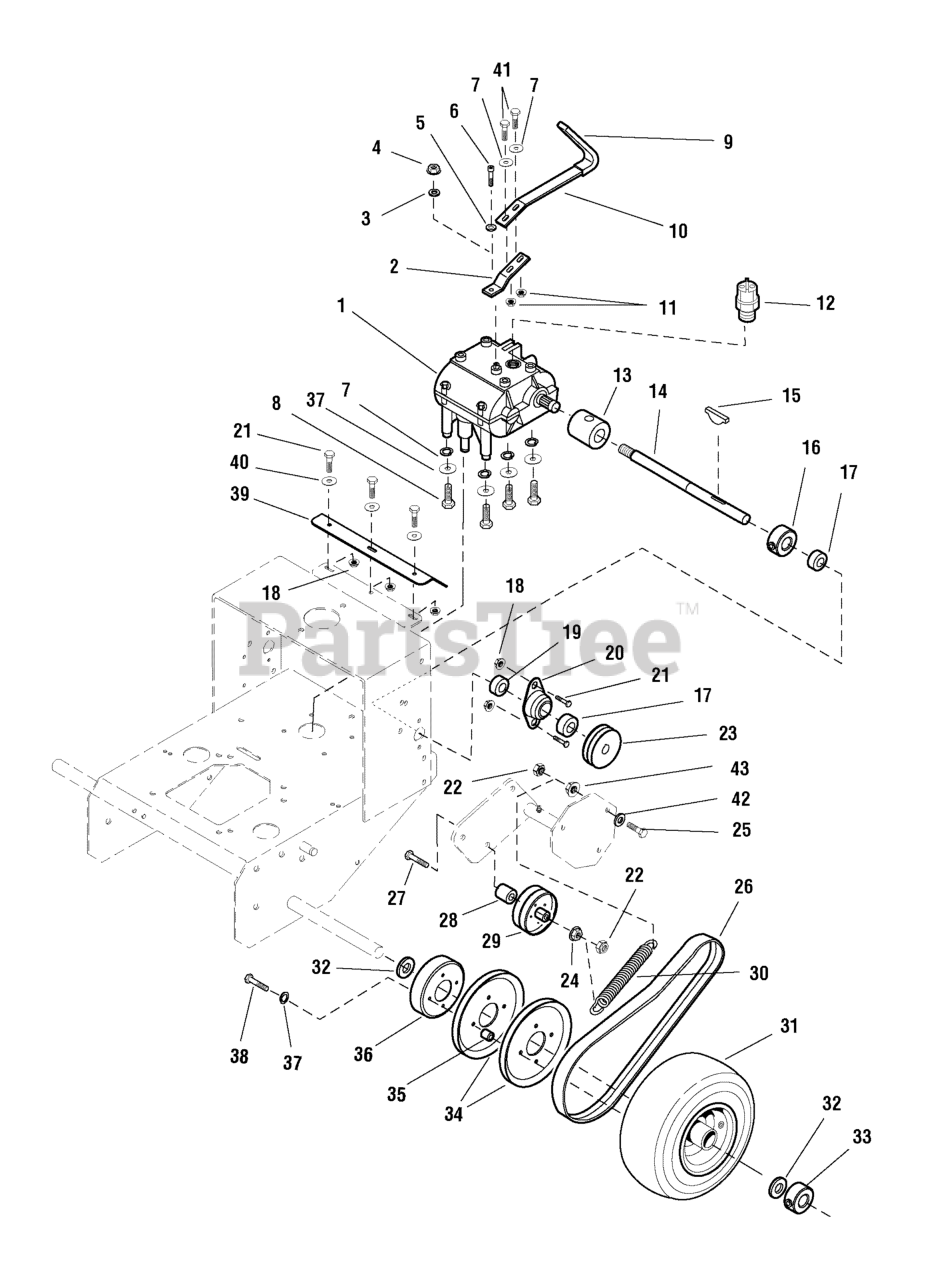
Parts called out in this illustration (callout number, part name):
1A	5 SPEED GEARBOX
1B	5 SPEED GEARBOX
2A	LEVER, Gear Selector
2B	LEVER, Gear Selector
3	WASHER, 3/8" GD9
4	NUT, 3/8-24 Hex Nylon Lock
5	WASHER, Retaining
6	BOLT, Allen Head, 1/4-28 x 5/8
7	WASHER, 5/16" SAE
8	BOLT, 5/16-18 X 3/4 GD5
9	GRIP, FOAM, 1/4 X 1 X 4.1
10	GEAR SELECTOR HANDLE
11	NUT, 5/16-18 HEX SERRATED FLANGE (LARGE)
12	SWITCH, NEUTRAL SAFETY
13	COUPLER
14	SHAFT
15	KEY, #9 Hi Pro Woodruff
16	COLLAR, 5/8" Split
17	SPACER, .63 x 1.06 x .23
18	NUT, 1/4-20 HEX SERR. FLANGE
19	BEARING
20	FLANGE BEARING
21	BOLT, 1/4-20 x 3/4
22	NUT, 3/8-16 HEX NYLON LOCK
23	PULLEY, Double-A Section
24	NUT, 3/8-16 Hex Nylon Flange
25	BOLT, 3/8-16 X 1-1/4" GD5 CZ
26	BELT, Double-A Section
27	BOLT, 3/8-16 X 3-1/2" GD5 CZ
28	SPACER, .52 X 1.00 X .88
29	PULLEY, Idler
30	SPRING, Extension
31	TIRE & WHEEL ASSEMBLY
32	WASHER, 1" SAE
33	COLLAR, 1" Split
34	PULLEY, Ground Drive
35	SPACER, Pulley
36	BRAKE DRUM
37	LOCK WASHER, 5/16
38	BOLT, 5/16-18 x 1-1/2
39	GUIDE, Gear Selector
40	WASHER, 1/4 SAE
41	BOLT, 5/16-18 X 1 GD5 YZ
42	WASHER, 3/8 SAE
43	NUT, 3/8-16 SERRATED FLANGE
